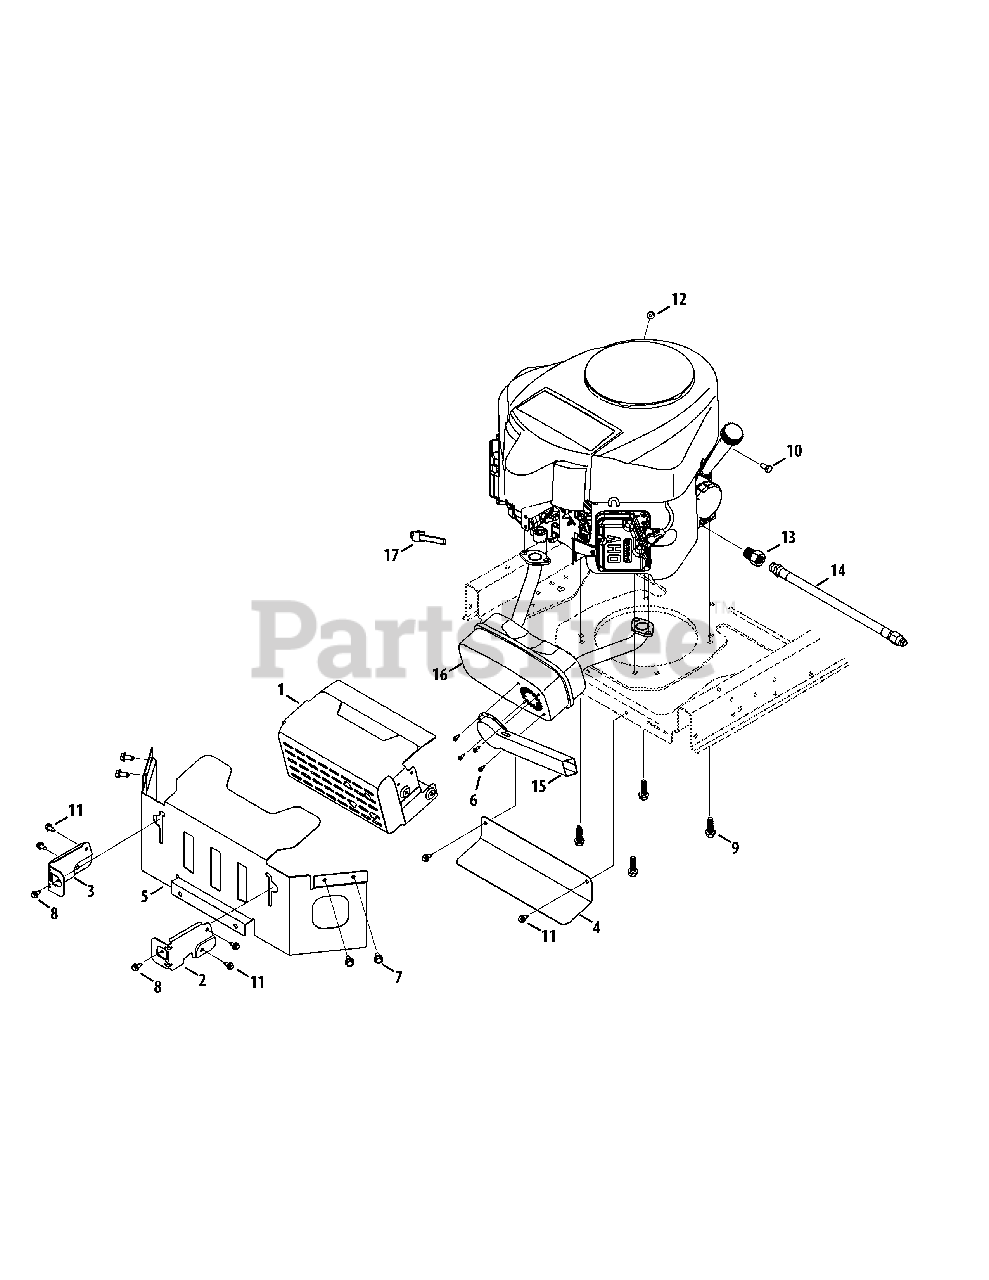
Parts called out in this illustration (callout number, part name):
1	Muffler Shield Assembly
2	Muffler Shield Bracket, RH
3	Muffler Shield Bracket, LH
4	Lower Heat Shield
5	Muffler Shield
6	Hex Washer Screw, #8-18 x .500
7	Hex Washer Screw, 5/16-18 x .750
8	Screw, 1/4-20 x .375
9	Screw, 3/8-16 x 1.25
10	Hex Cap Screw, M8-1.25 x 16
11	Hex Washer Screw, 1/4-20 x .625
12	Flange Lock Nut, 1/4-20
13	Fitting, 1.0 Hex x M20
14	Oil Drain Hose
15	Muffler Deflector Long
16	Twin Muffler
17	Cable Tie
